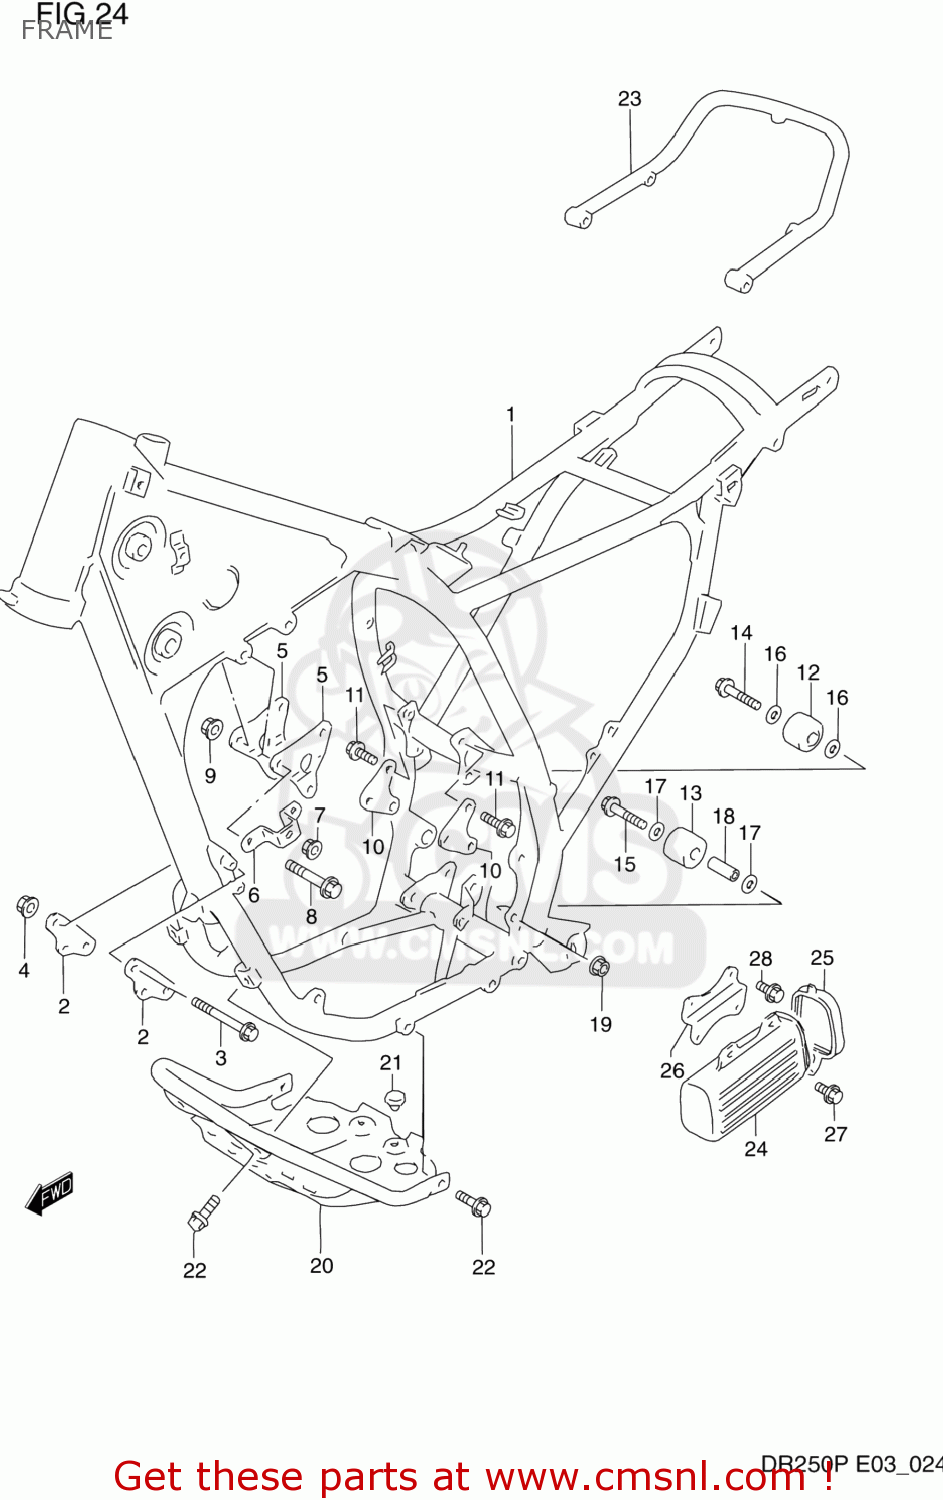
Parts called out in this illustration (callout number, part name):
1	FRAME
2	PLATE,ENGINE MOUNT FR
3	BOLT
4	NUT
5	PLATE,ENGINE MOUNT UPR
6	PLATE,FUEL TANK STOPPER
7	CUSHION
8	BOLT(8X70)
9	NUT
10	PLATE,ENGINE MOUNTING,REAR
11	BOLT(8X16)
12	ROLLER,CHAIN
13	ROLLER,CHAIN CONTROL
14	BOLT(8X38)
15	BOLT 8X45
16	WASHER(8.5X13X1.6)
17	WASHER
18	SPACER (8.6X13.8X28)
19	NUT 8MM
20	PROTECTOR,ENGINE
21	CUSHION
22	BOLT 8X12
23	GRIP,RR
24	HOLDER,TOOL
25	CAP,TOOL HOLDER
26	PLATE,TOOL HOLDER FITING
27	BOLT M6X16
28	BOLT
